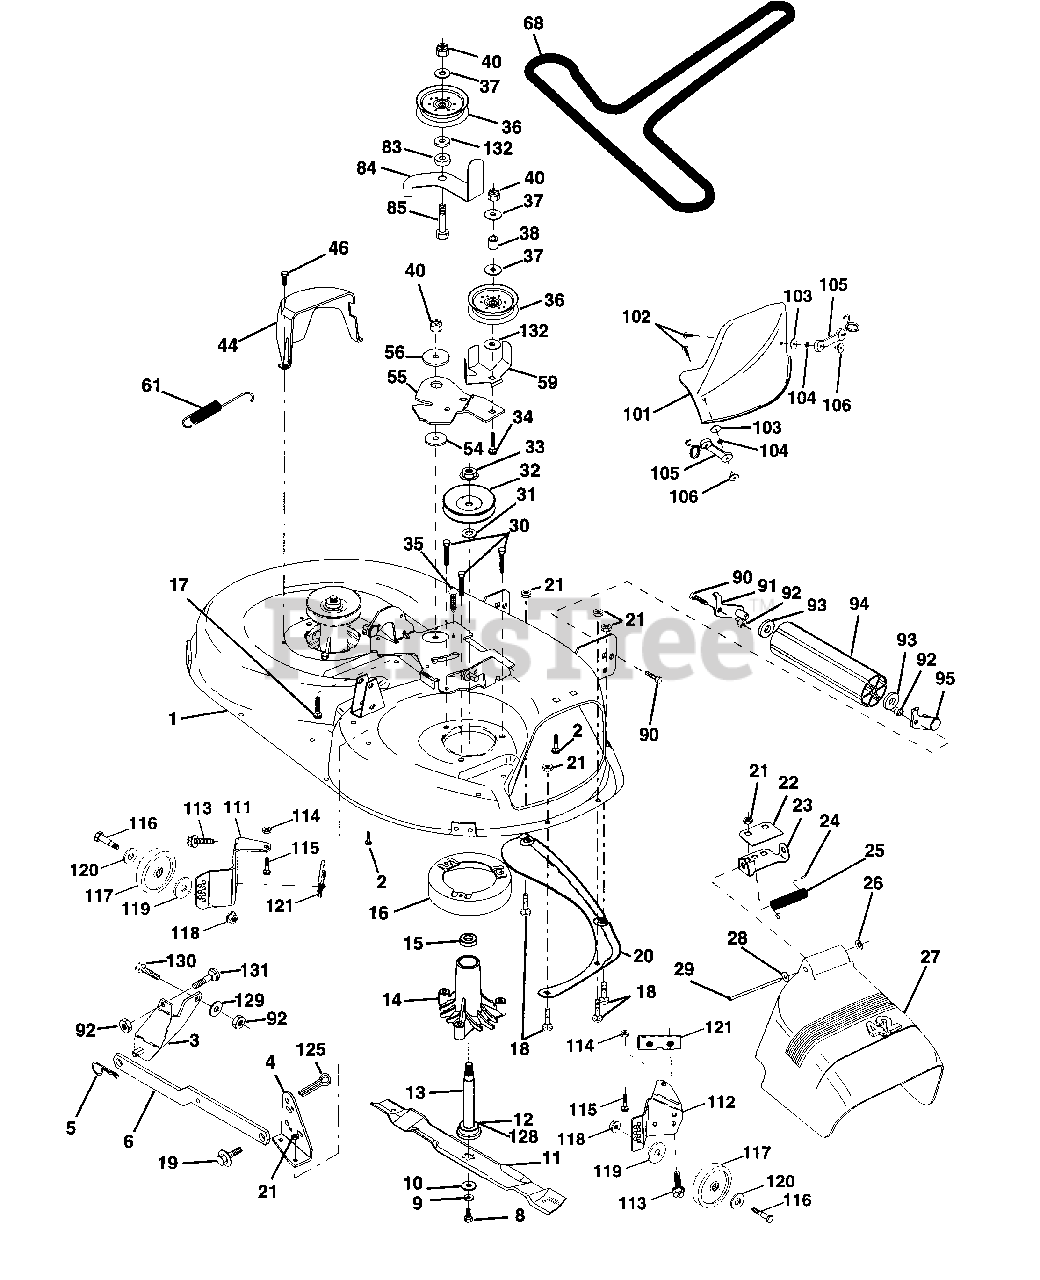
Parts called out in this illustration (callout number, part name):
1	Housing Asm Mower 42"94 T-Path
2	Bolt Rdhd Sqnk 5/16-18unc X3/4
3	Bracket Asm Fr Sway Bar 38/42
4	Bracket Asm Deck 42"sway Bar
5	Retainer Spring
6	Arm Suspension Rear
8	Bolt 3/8-24x1 25 Gr8 Patched
9	Washer Lock Hvy 3/8 Unplated
10	Washer Hard Blade Mower Vented
11	Blade Mower Mulching 42"
12	Bearing Ball #6204 (Mandrel)
13	Shaft Asm W/lower Bearing
14	Housing Mandrel Vented(machd)
15	Bearing Ball Mandrel
16	Stripper Round Mower
17	Bolt Rdhd Sqnk 3/8-16 X 2-1/4
18	Bolt Carr 5/16-18 X 5/8
19	Bolt Shoulder
20	Baffle Vortex 42
21	Nut Crown Lock 5/16-18
22	Stiffener Bracket 42"deck
23	Bracket Deflector Mower 42"
24	Cap Sleeve 80x 112 Blk Mower
25	Spring Torsion Deflector 2 52
26	Nut Push Phos & Oil
27	Shield Deflector Mower 42" Blk
28	Washer 11/32 X 5/8 X 16 Ga
29	Rod Hinge 42"6 75 Wlg
30	Screw Thdrol Hex Hd Zinc Mwr.
31	Washer Spacer Mower Vented
32	Pulley Mandrel 42"
33	Nut 9/16top Lock Flng Cntr
34	Bolt RDHD 3/8-16 UNC x 2-3/4 Gr. 5
35	Fastner Christmas Tree
36	Pulley Idler Flat 3 060
37	Washer 1 3/32 X 13/16 X 16 Ga
38	Spacer Spring Stop Idler
40	Nut Lock 3/8-16 Unc
44	Guard Mandrel LH Black
46	Screw Thdrol 1/4-20x5/8
54	Washer Hardened
55	Arm Idler 42"mower LT/YT
56	Spacer Retainer Pm Mower
59	Guard, Belt
61	Spring Ext. Elect
68	V-Belt Mower
83	Washer Sintered
84	Keeper Belt Idler
85	Bolt Carriage 3/8-16 x 2-1/4 Gr.5
90	Bolt Fin Hex 3/8-16unc X 1
91	Bracket Asm Noseroller LH
92	Nut Lock Hex w/Ins. 3/8-16 UNC
93	Washer 17/32 X 7/8 X 16 Ga
94	Roller Nose 38 & 42
95	Bracket Asm Noseroller RH
101	Cover Mulching 42" Blk
102	Screw
103	Washer #10
104	Washer Lock #10
105	Latch Asm Bagger
106	Nut Weld .327/.304 #10-24
111	Bracket Wheel Gauge Lh 42" Deck
112	Bracket Gauge Wheel Rh 42" Deck
113	Screw Thdrol 5/16-18 x 3/4 TYT
114	Nut Keps 5/16 - 18 UNC
115	Bolt Carriage 5/16 - Unc x 1/2
116	Bolt Shld "A" 2.41 "B" 1.66
117	Wheel Gauge blk. 4.93
118	Nut Centerlock 3/8 - 16 UNC
119	Washer 3/8 x 7/8 x 14 Ga.
120	Washer 17/32 x 15/16 x 12 Ga.
125	Cotter Pin
128	Washer Felt
129	Washer 13/32 x 13/16 x 12 Ga.
130	Bolt Fin Hex 3/8-16 UNC x 1 Gr. 5
131	Bolt Rdhd Sqnk 3/8-16 x t
